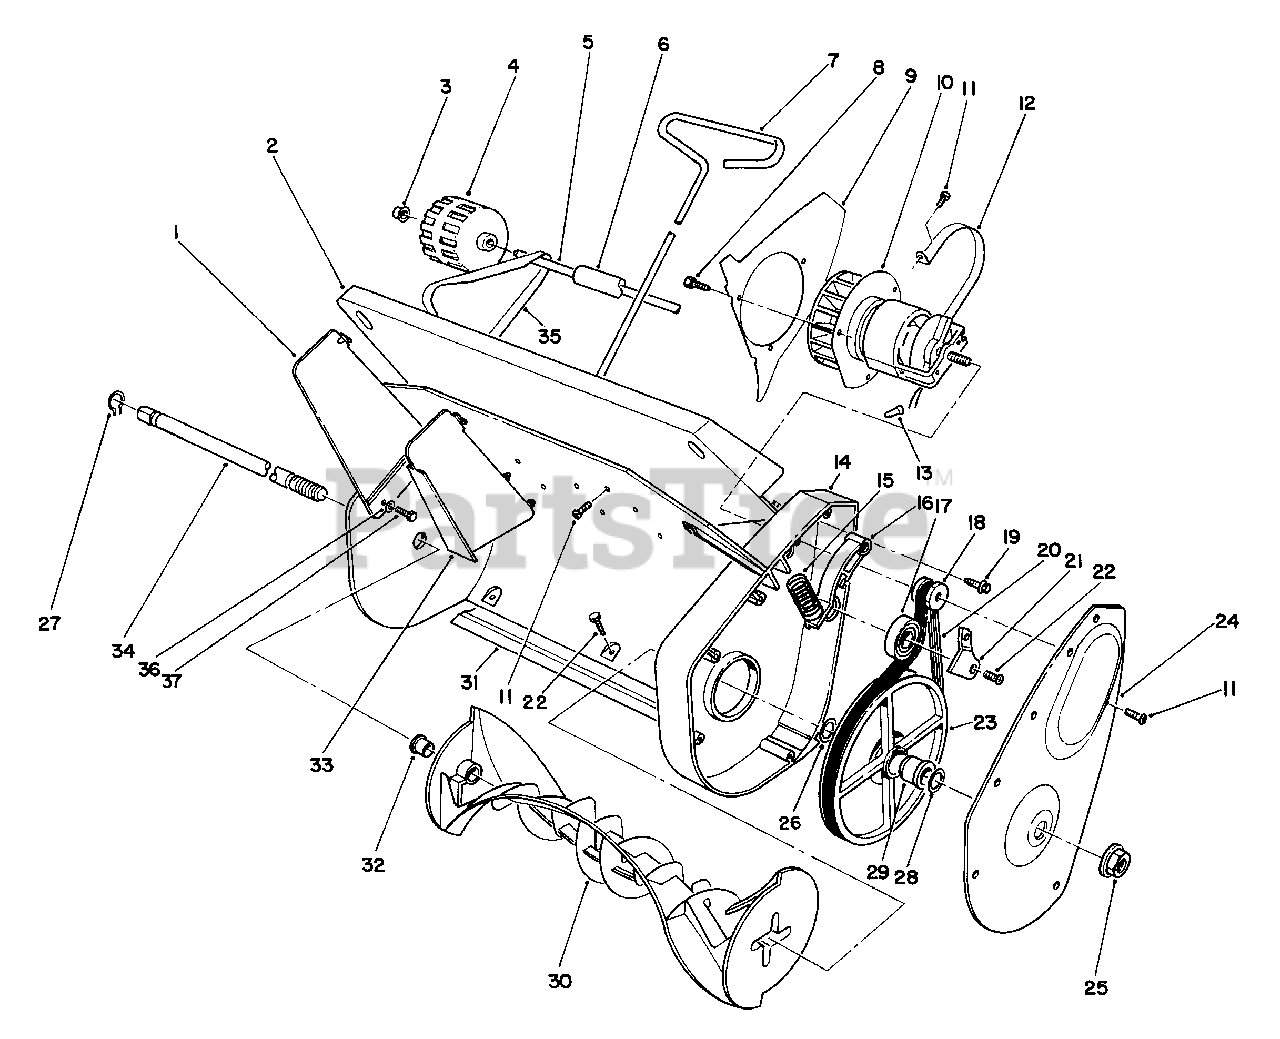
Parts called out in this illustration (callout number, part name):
1	Vane-Outer
2	Mount-Vane
3	Nut-Push On
5	Shaft-Axle
6	Sleeve-Axle
7	Rod-Vane Adjustment
8	Screw-Self Tapping
9	Baffle-Air
11	Screw-Self Tap. Pan Hd.
12	Mount-Motor
13	Connector-Wire
15	Spring-Compression Idler
16	Arm-Idler
17	Bearing-Ball
18	Pulley Drive
19	Screw-Hex. Washer Hd.
20	Belt-Drive
21	Retainer-Idler Pulley
22	Screw-Self Tap. Pan Hd.
23	Pulley-Driven
24	Cover-Belt Case
25	Nut-Flange Lock
26	Washer-Thrust
27	Ring-Retaining
28	Washer-Thrust
29	Bushing-Rotor
32	Bushing-Rotor
33	Vane-Center
34	Shaft-Rotor
35	Bracket-Wheel R.H.
37	Screw-Self Tapping
